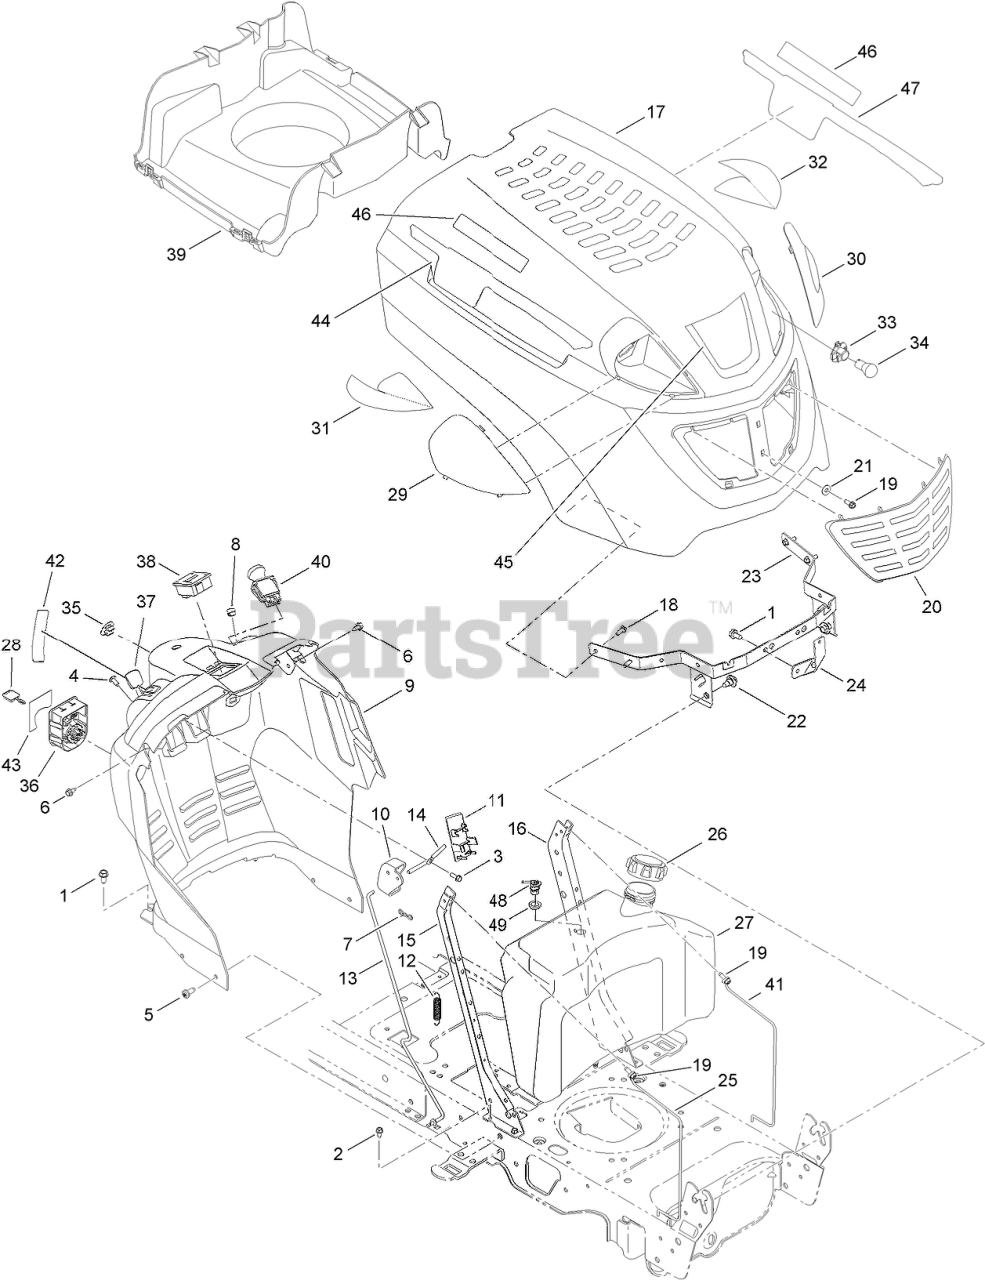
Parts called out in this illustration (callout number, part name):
1	SCREW-TAP
2	SCREW-HWHTF
3	SCREW-TAP
4	SCREW-TAP
5	SCREW-TAP
6	SCREW-HWH
7	PIN-COTTER
8	CAP-PLUG, HOLE
9	DASH-ELECTRIC, PTO
10	LEVER-DASH
11	COVER-CRUISE
12	SPRING-EXTENSION
13	ROD-LATCH
14	ROD-LEVER, BENT
15	SUPPORT-DASH, PLATE (RH)
16	SUPPORT-DASH, PLATE (LH)
19	SCREW-TAP
21	WASHER-FLAT
22	BOLT-SHOULDER, TAP
23	BRACKET-PIVOT
24	BRACKET-SUPPORT, HOOD
25	ROD-SUPPORT
26	CAP-FUEL
27	TANK-FUEL
28	KEY-IGNITION
29	LENS-RH
30	LENS-LH
31	REFLECTOR-RH
32	REFLECTOR-LH
33	SOCKET-HEADLIGHT
34	LAMP-12V, MINIATURE
35	PLUG-CHOKE
36	MODULE-SWITCH, IGNITION
37	CABLE-THROTTLE AND CHOKE
38	METER-HOUR
39	PLENUM-HOOD
40	SWITCH-ELECTRIC, PTO
41	ROD-SUPPORT, LH TANK
42	DECAL-THROTTLE
43	DECAL-SWITCH, IGNITION
44	DECAL-HOOD, RIGHT SIDE
45	DECAL-HOOD
47	DECAL-HOOD, LEFT SIDE
48	Valve-Rollover, Grommet
49	Grommet-Rubber
